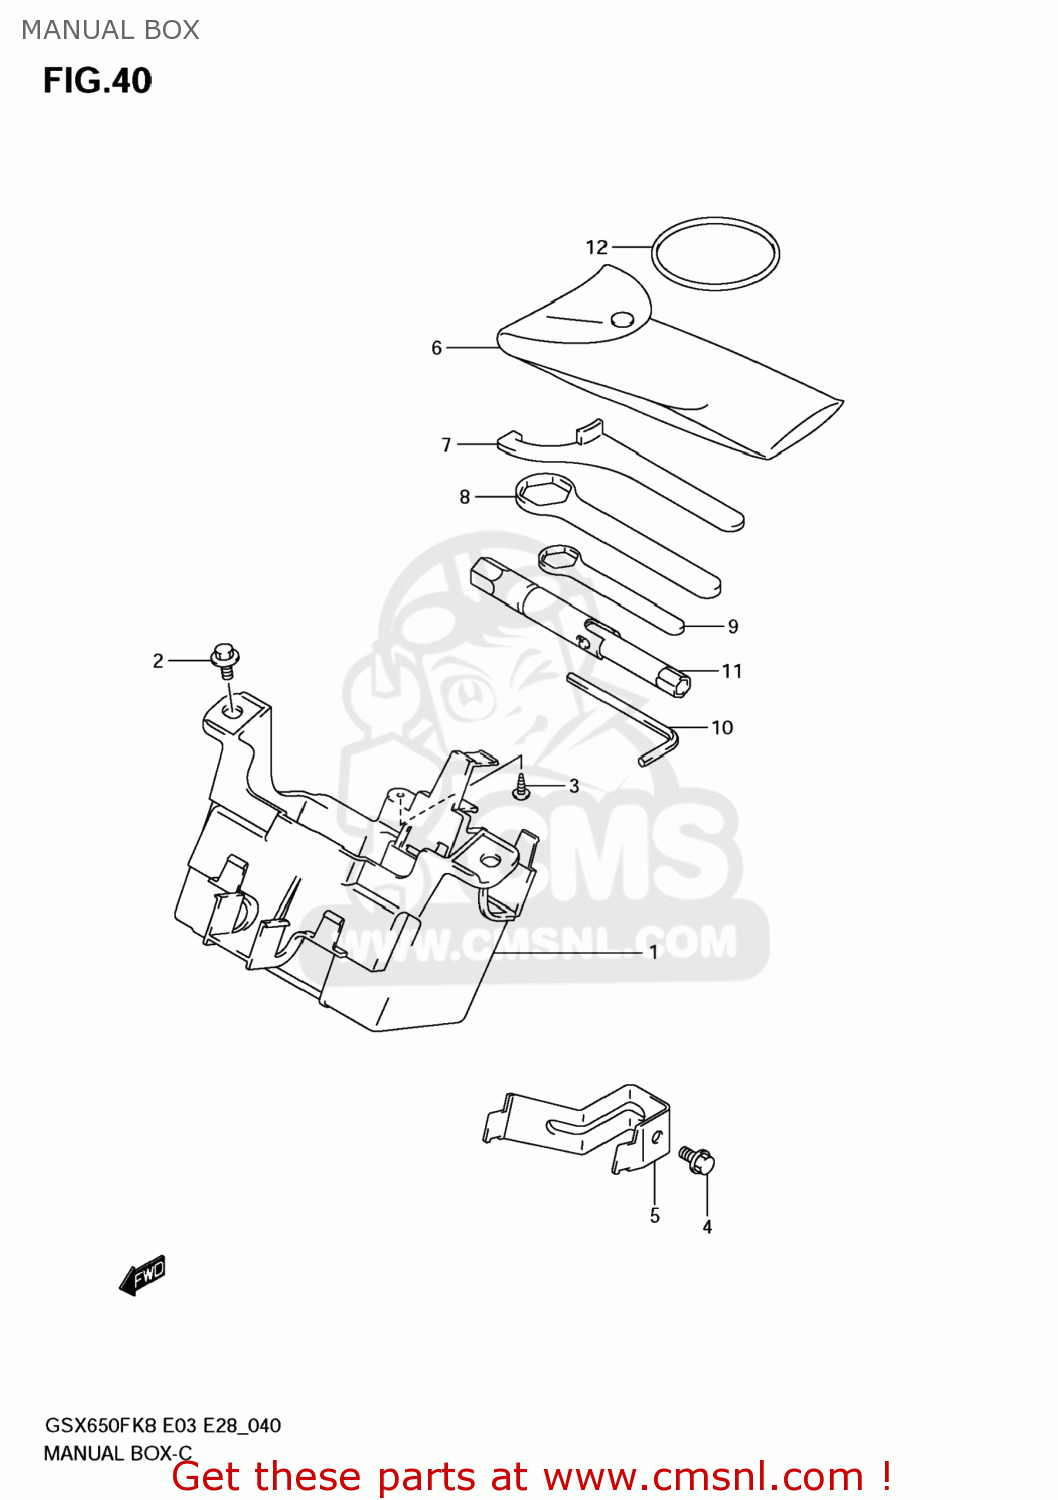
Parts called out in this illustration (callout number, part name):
1	HOLDER,BATTERY
2	BOLT
3	SCREW
4	BOLT
5	PLATE,FUSE BOX
6	TOOL ASSY
7	CLAMP
8	RING SPANNER
9	RING, SPANNER
10	SPANNER,HEXAGON
11	SPARK PLUG WRENCH
12	O RING(D:3.5,ID:61)
